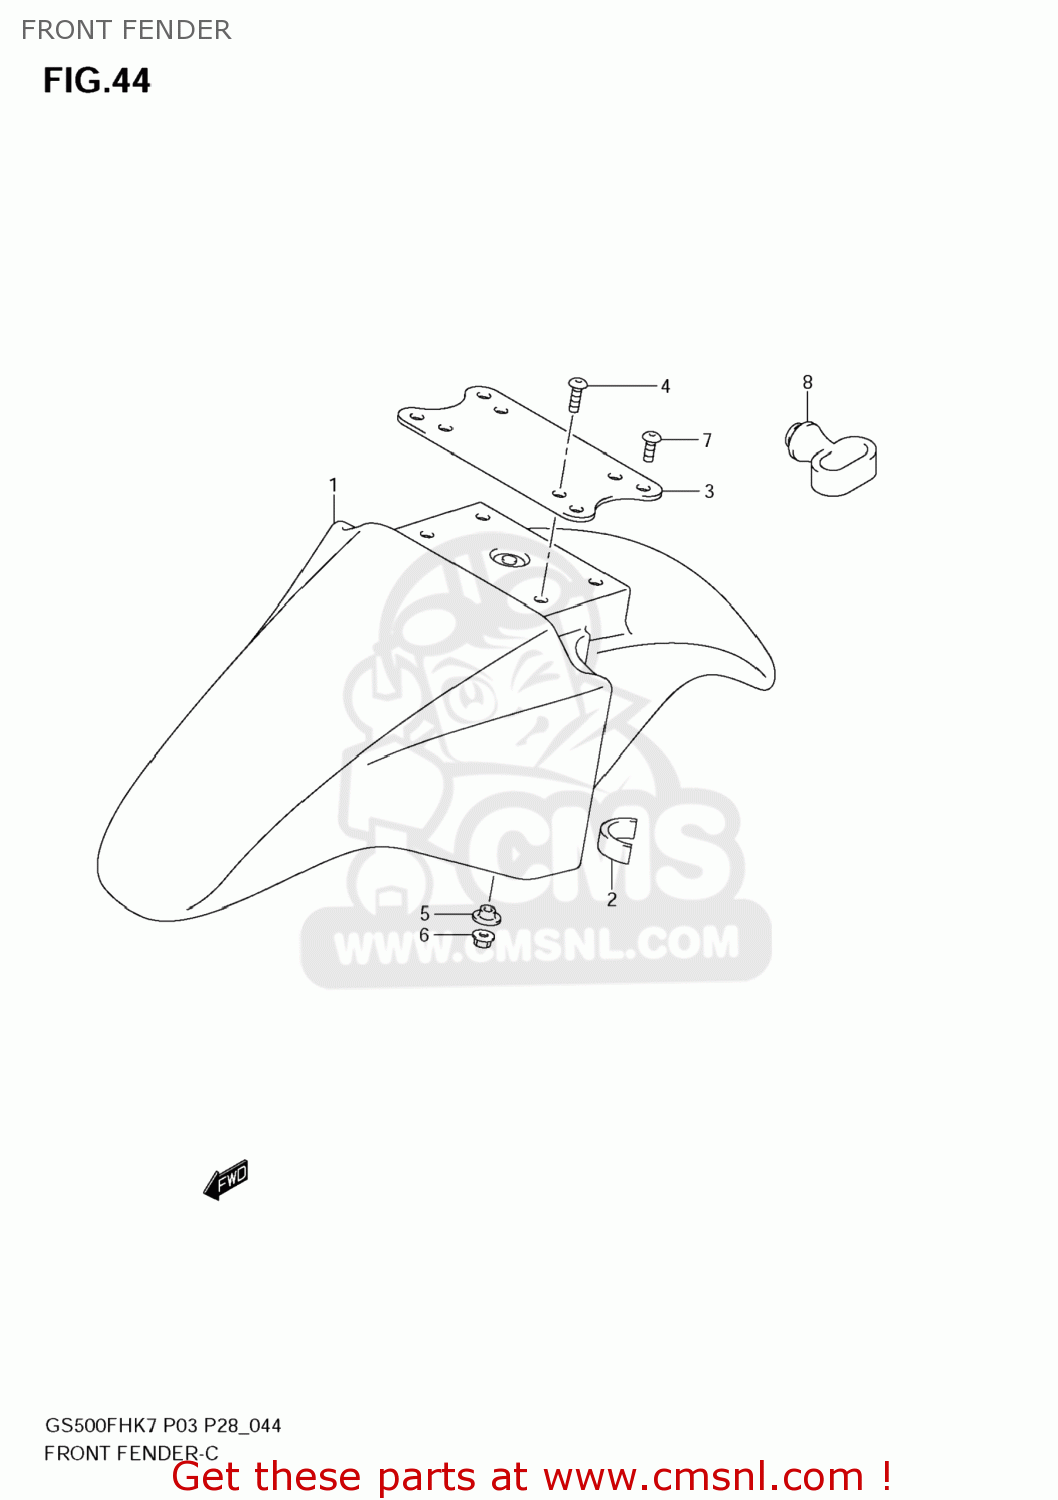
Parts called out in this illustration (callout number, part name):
1	FENDER,FRONT
2	CUSHION
3	BRACE, FRONT FENDER (BLACK)
4	SCREW(5X18)
5	WASHER
6	NUT
7	SCREW(6X12)
8	GUIDE,CABLE
